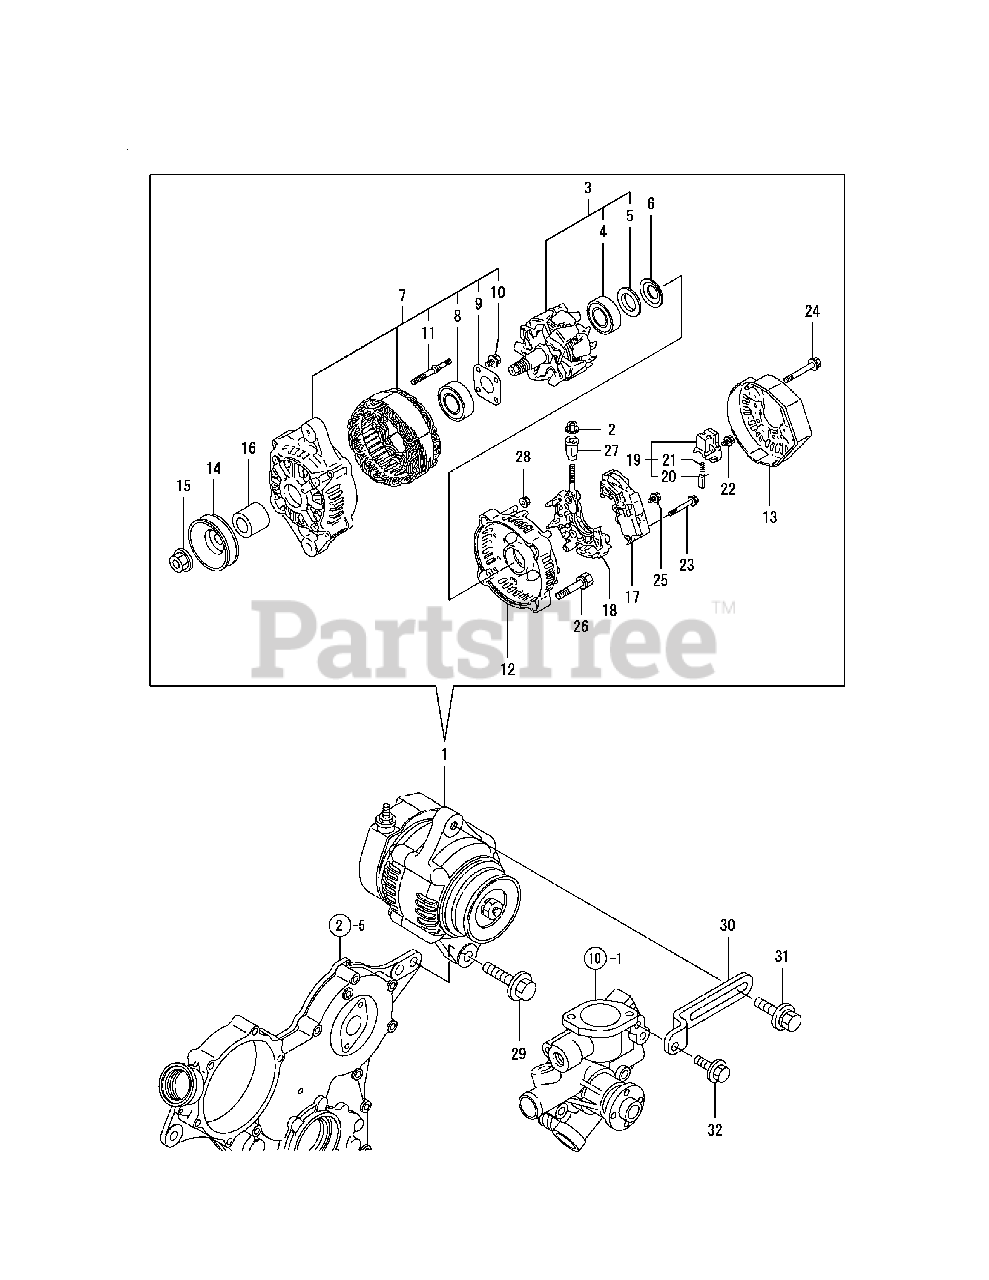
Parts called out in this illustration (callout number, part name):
5	COVER, BEARING
7	FLAME ASSY, DRIVE
12	FLAME ASSY, REAR
17	REGULATOR ASSY
25	SCREW W/WASHER
27	INSULATION BUSH
29	BOLT M10X 45 PLATED
30	ADJUSTER, BELT
32	BOLT M 8X 20 PLATED
